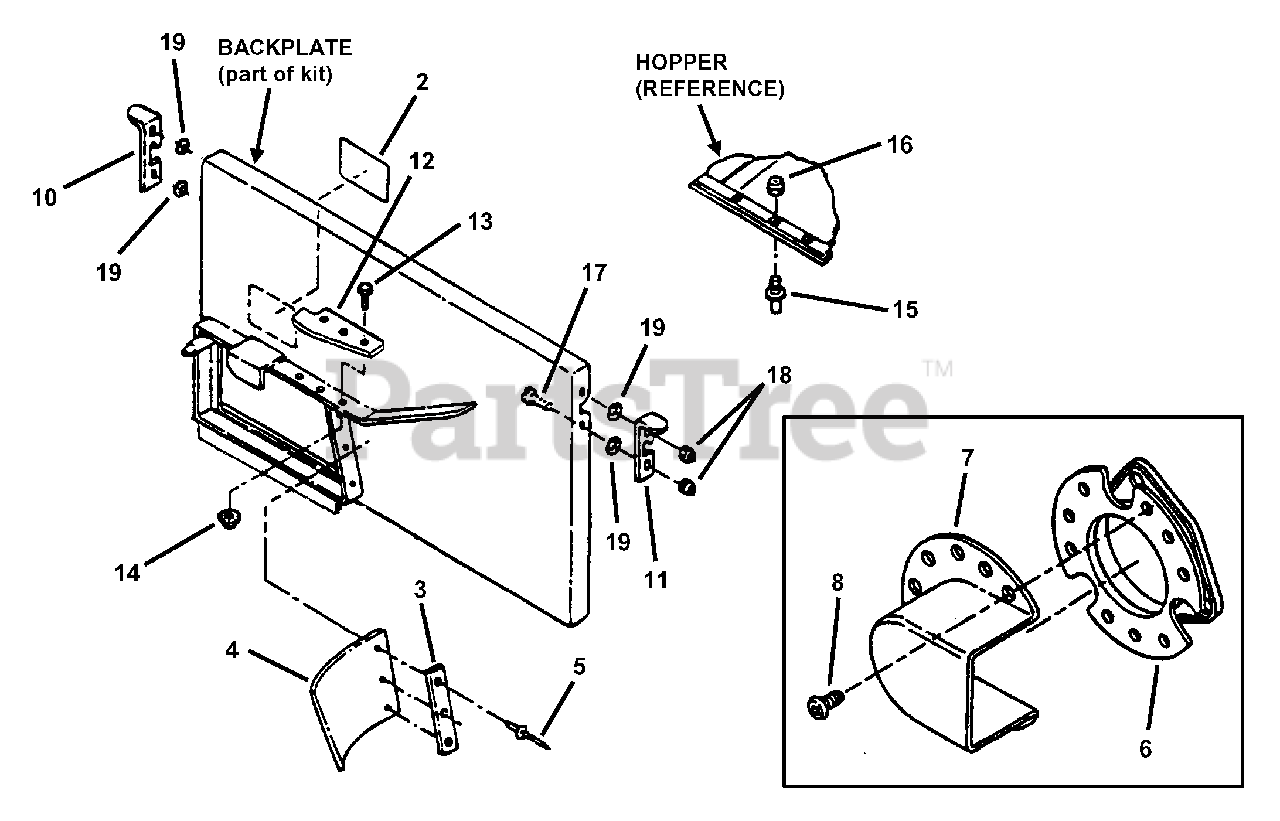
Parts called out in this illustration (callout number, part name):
2	DECAL, Warning
3	PLATE, Backing
4	STRIP, Side Sealing
5	POP RIVET
6	CAP, Deflector
7	DEFLECTOR, Exhaust
8	SCREW, Deflector Mounting
10	LATCH, Left Side
11	LATCH, Right Side
12	STRIP, Top Seal
13	SCREW, 1/4-20 x 3/4" Hex Head Cap
14	NUT, 1/4-20 Hex Flange Lock
15	STUD, 3/8-24 Thread
16	NUT, 3/8-24 Hex Nyloc
17	SCREW, #10-24 x 5/8" Pan Head
18	NUT, #10-24 Hex Nyloc
19	WAVE WASHER (spring)
